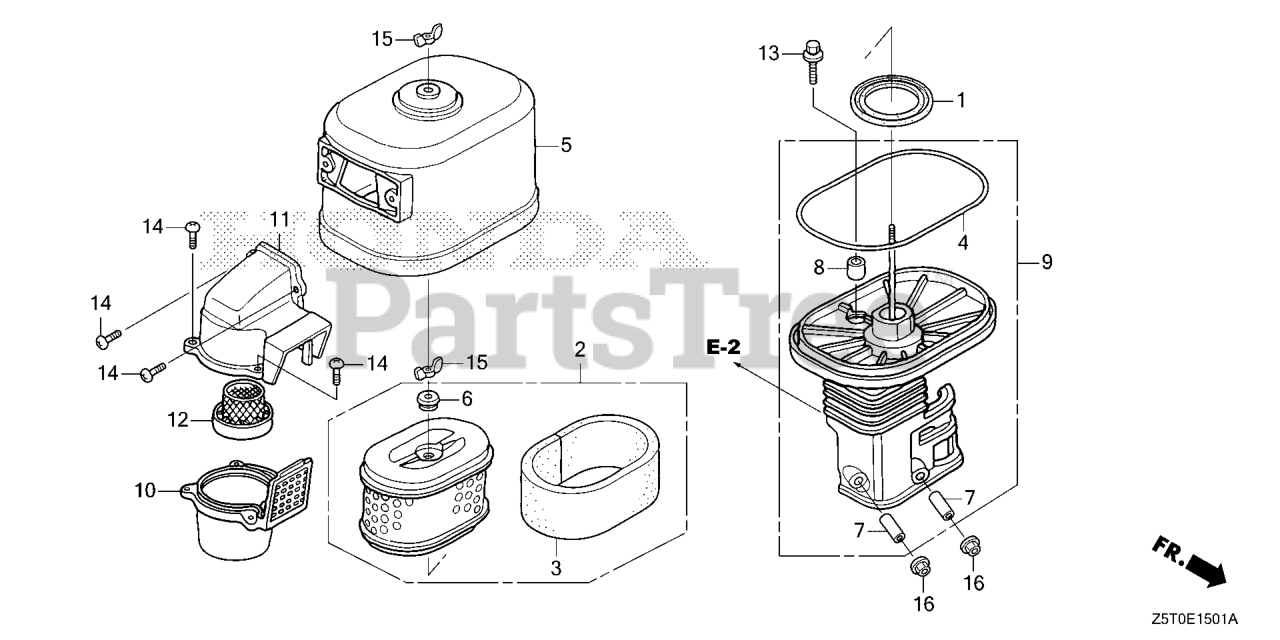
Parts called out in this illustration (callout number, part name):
1	GASKET, ELBOW
2	ELEMENT, AIR CLEANER
3	FILTER (OUTER)
4	SEAL, AIR CLEANER COVER
5	COVER, AIR CLEANER (CYCLONE)
6	GROMMET, AIR CLEANER
7	COLLAR, AIR CLEANER
8	COLLAR B, AIR CLEANER
9	ELBOW, AIR CLEANER
10	CASE, PRE AIR CLEANER
11	CAP, PRE AIR CLEANER
12	GUIDE, PRE AIR CLEANER
13	BOLT-WASHER (6X22)
14	SCREW, PAN (5X16.5)
15	WINGNUT, TOOL BOX SETTING
16	NUT, FLANGE (6MM)
